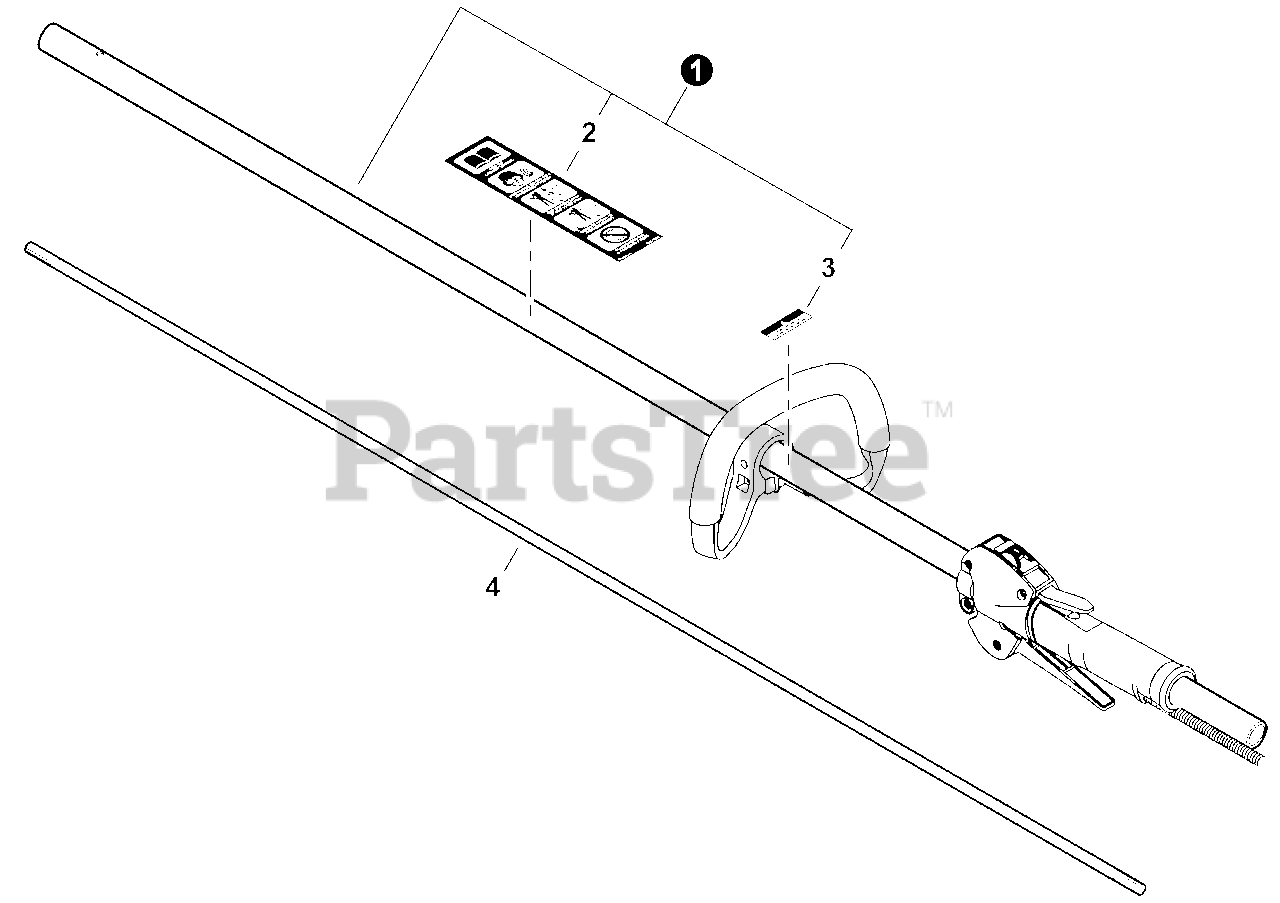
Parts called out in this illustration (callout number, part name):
1	MAIN PIPE ASSY
2	LABEL, CAUTION
3	LABEL, HANDLE
4	MAINSHAFT
